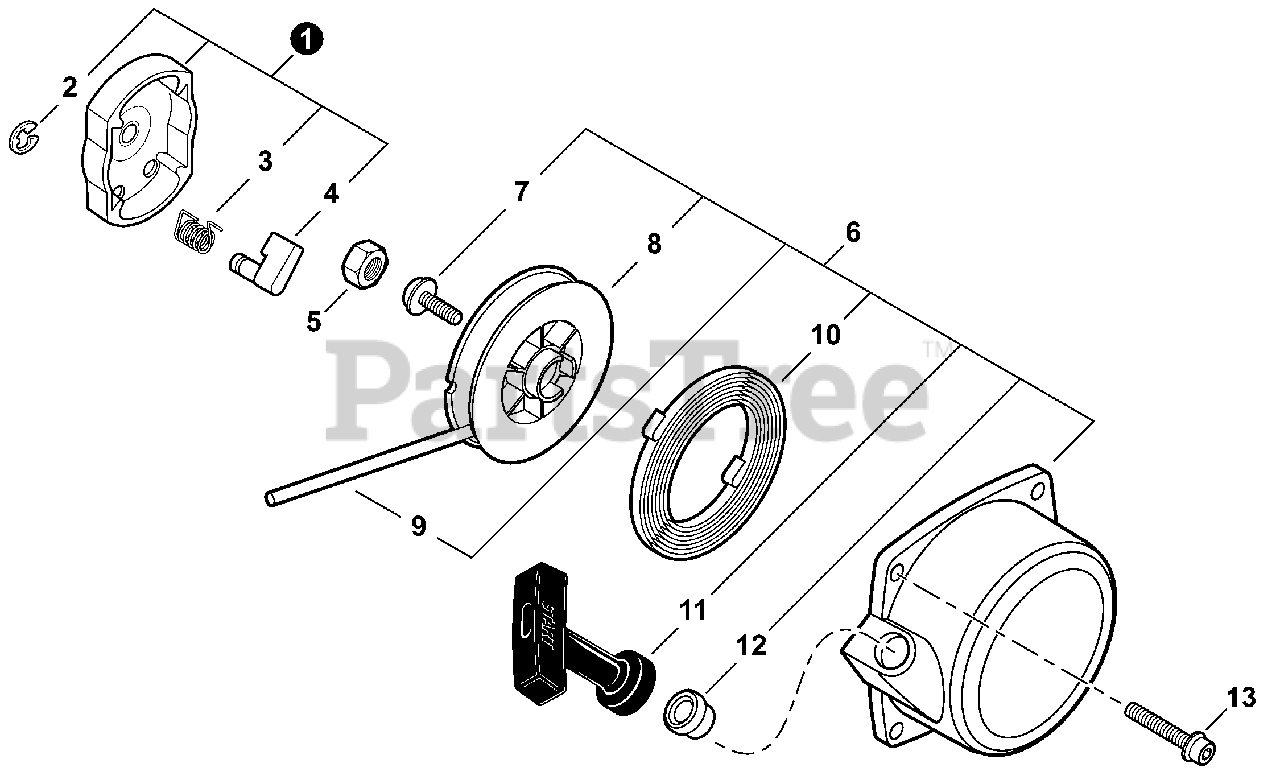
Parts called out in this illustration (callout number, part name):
1	PULLEY ASSY, STARTER
2	E-RING 4
3	SPRING, RETURN
4	PAWL
5	NUT 8×1.25
6	STARTER ASSY, RECOIL
8	REEL, ROPE
9	ROPE, STARTER 3.8×1150
10	SPRING, RECOIL
11	GRIP, STARTER
12	GUIDE, ROPE
13	BOLT 5×20
